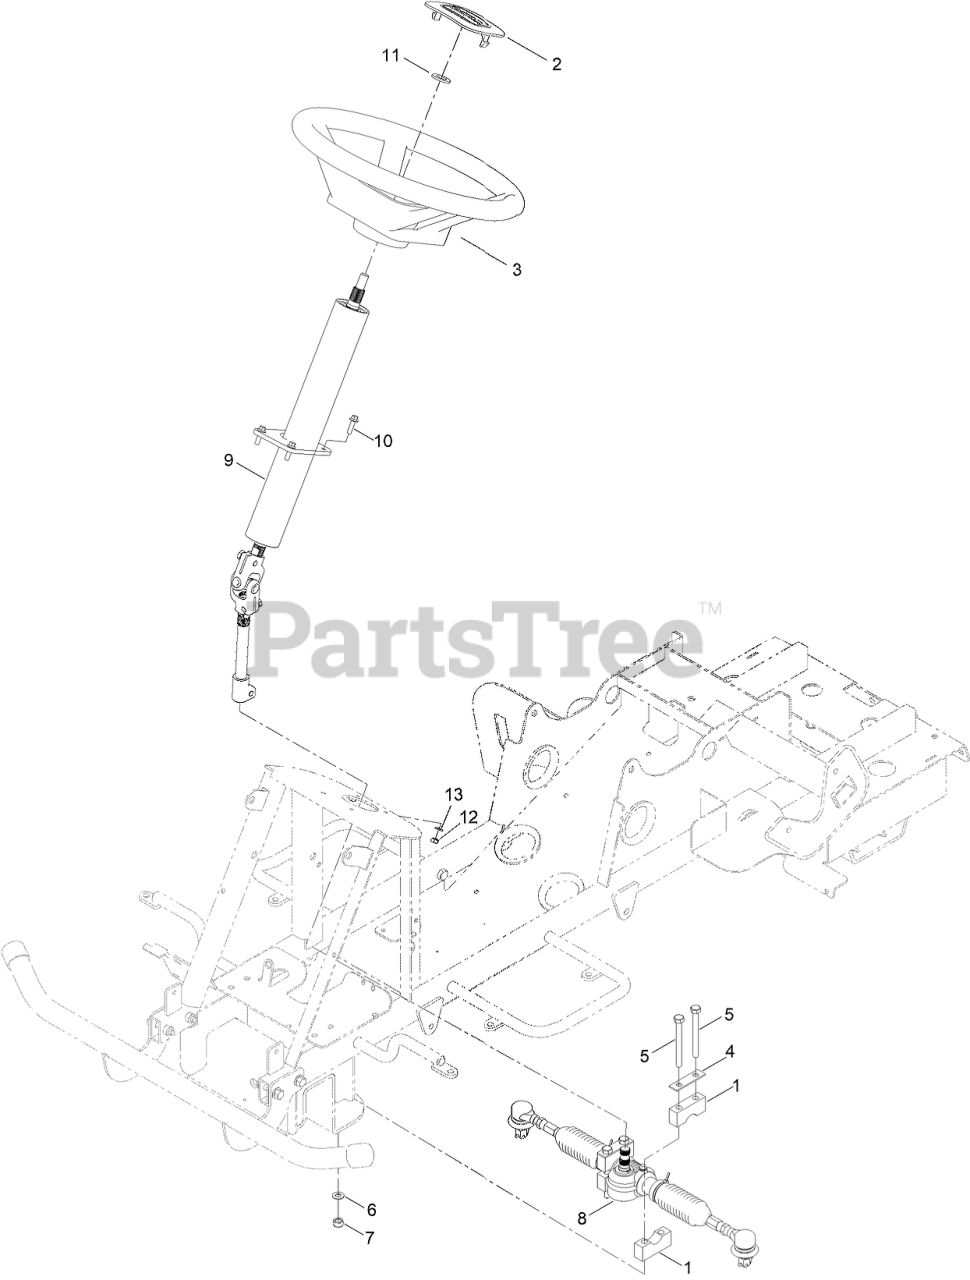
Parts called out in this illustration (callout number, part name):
1	MOUNTING BLOCK, STEERING RACK
2	COVER, STEERING WHEEL
3	STEERING WHEEL
4	PLATE, MOUNTING BLOCK
6	WASHER-PLAIN
7	NUT-HEX, NI
8	STEERING RACK ASM
9	UPPER STEERING ASM
10	BOLT-M6
11	WASHER-PLAIN
12	NUT-M6
13	WASHER-PLAIN
